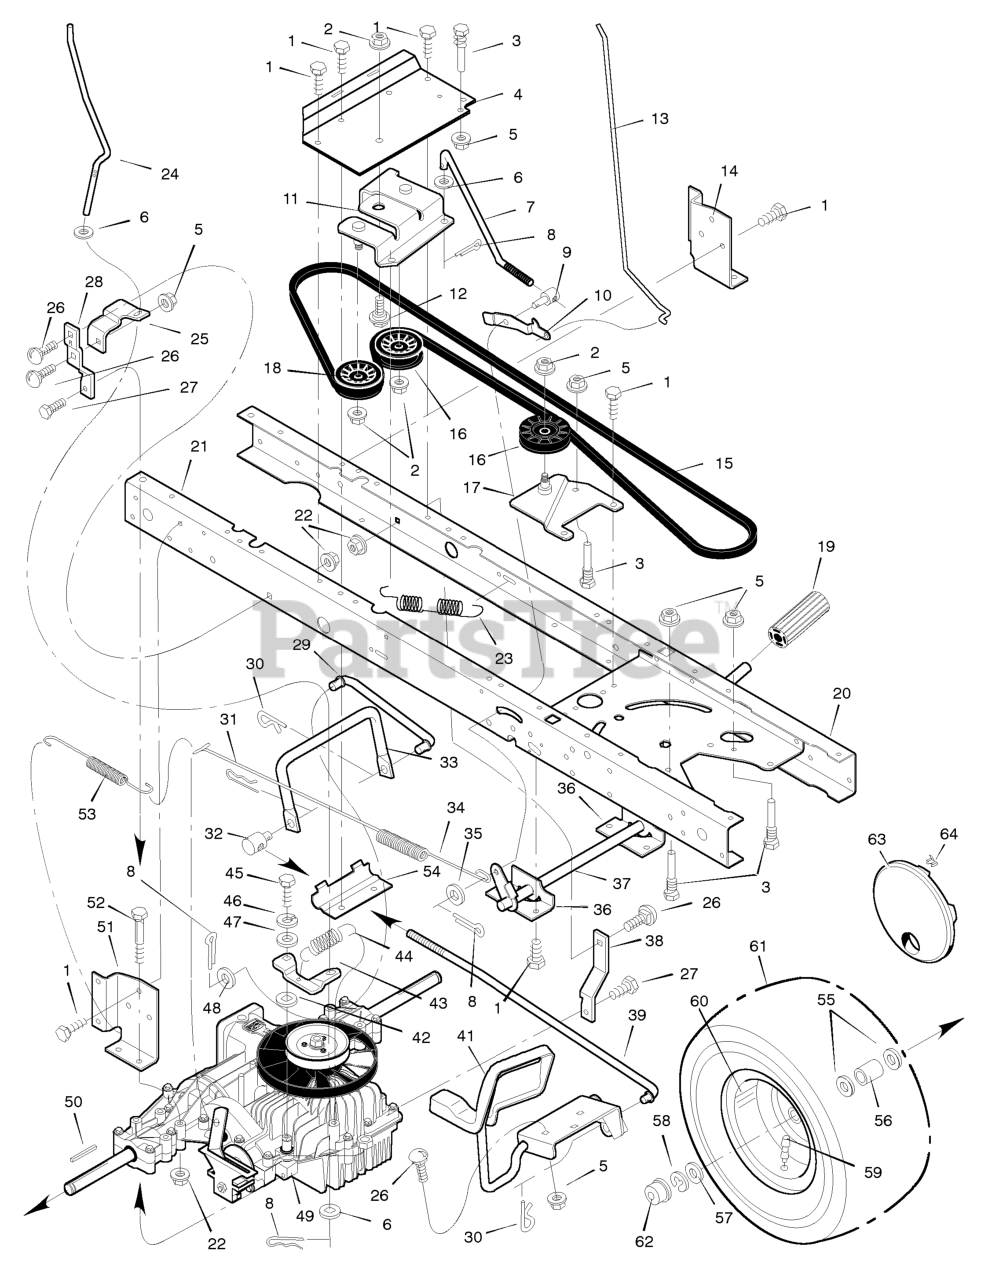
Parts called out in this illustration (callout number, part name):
2	Nut, Flange
3	Guide, Belt
4	Bracket, Idler
5	Locknut
6	Washer
7	Rod, Clutch
8	Pin, Cotter
9	Adjuster
10	Latch, Parking Brake
11	Bracket Assembly, Idler
12	Bolt, Shoulder
13	Rod, Parking Brake
14	Bracket, Transaxle
16	Pulley, Idler
17	Arm Assembly, Idler
18	Pulley, Idler
19	Pedal
20	Frame, Left
21	Frame, Right
22	Nut, Flange
23	Spring, Extension
24	Rod, Disconnect
25	Bracket, Disconnect
26	Bolt, Carriage
28	Strap, Right Torque
29	Rod, Link
30	Pin, Hair
31	Pin, Hair
32	NUT, Adjusting, 1/2-13
33	Rod, Yoke
34	Spring, Extension
35	Washer
36	Bracket, Pivot
37	Lever, Clutch/Brake
38	BRACKET, Torque Strap, LH
39	Rod, Link
41	Pedal, Speed Control
43	Arm, Disconnect
44	Spring
46	Lockwasher
48	Washer
49	Transaxle **
50	Key, Square
51	Bracket, Right Transaxle
52	Bolt
53	Spring, Extension
54	Clamp, Transaxle
56	Spacer
59	Valve Stem
60	Wheel & Tire Assembly
62	Cap, Hub
63	Disc, Wheel
64	Clip, Retainer
